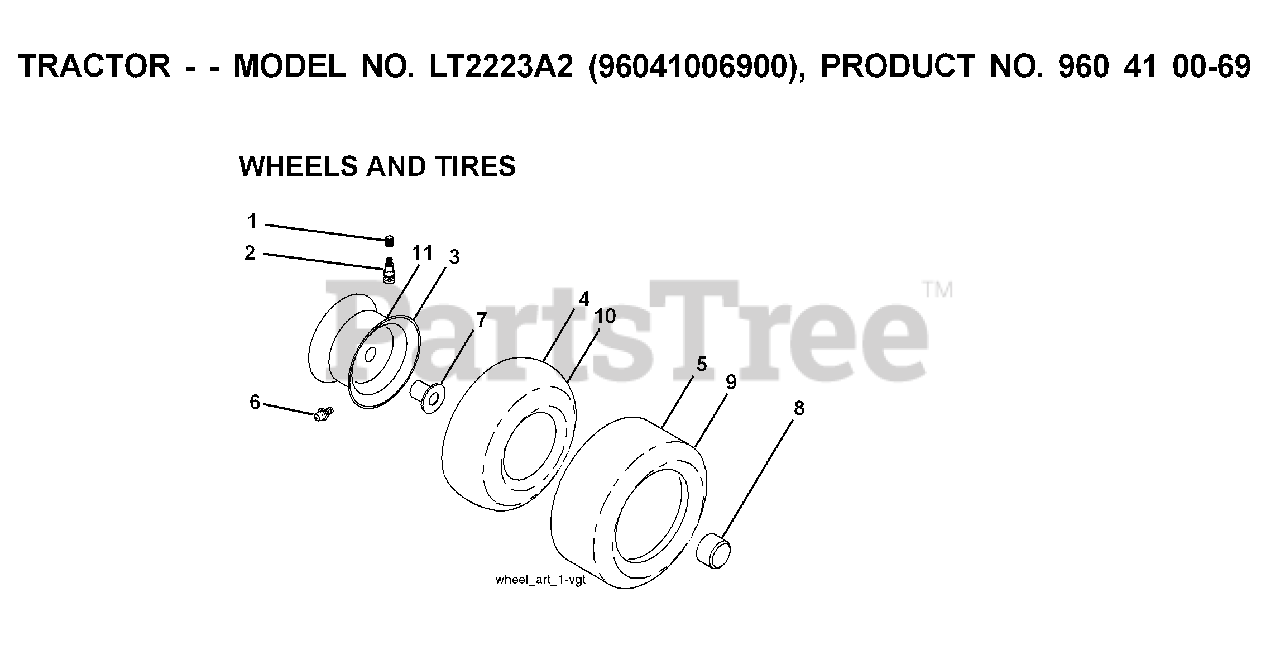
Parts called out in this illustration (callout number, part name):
1	VALVE CAP
2	VALVE STEM LT
3	RIM ASM 6" FRONT SILVER
4	TUBE.5.3/4.5/6
5	TIRE HEAVY DUTY
6	FITTING LT
7	BEARING T
8	CAP, AXLE BLK
9	TIRE.TS.20X10-8
10	TUBE
11	RIM ASM 8" REAR SILVER
